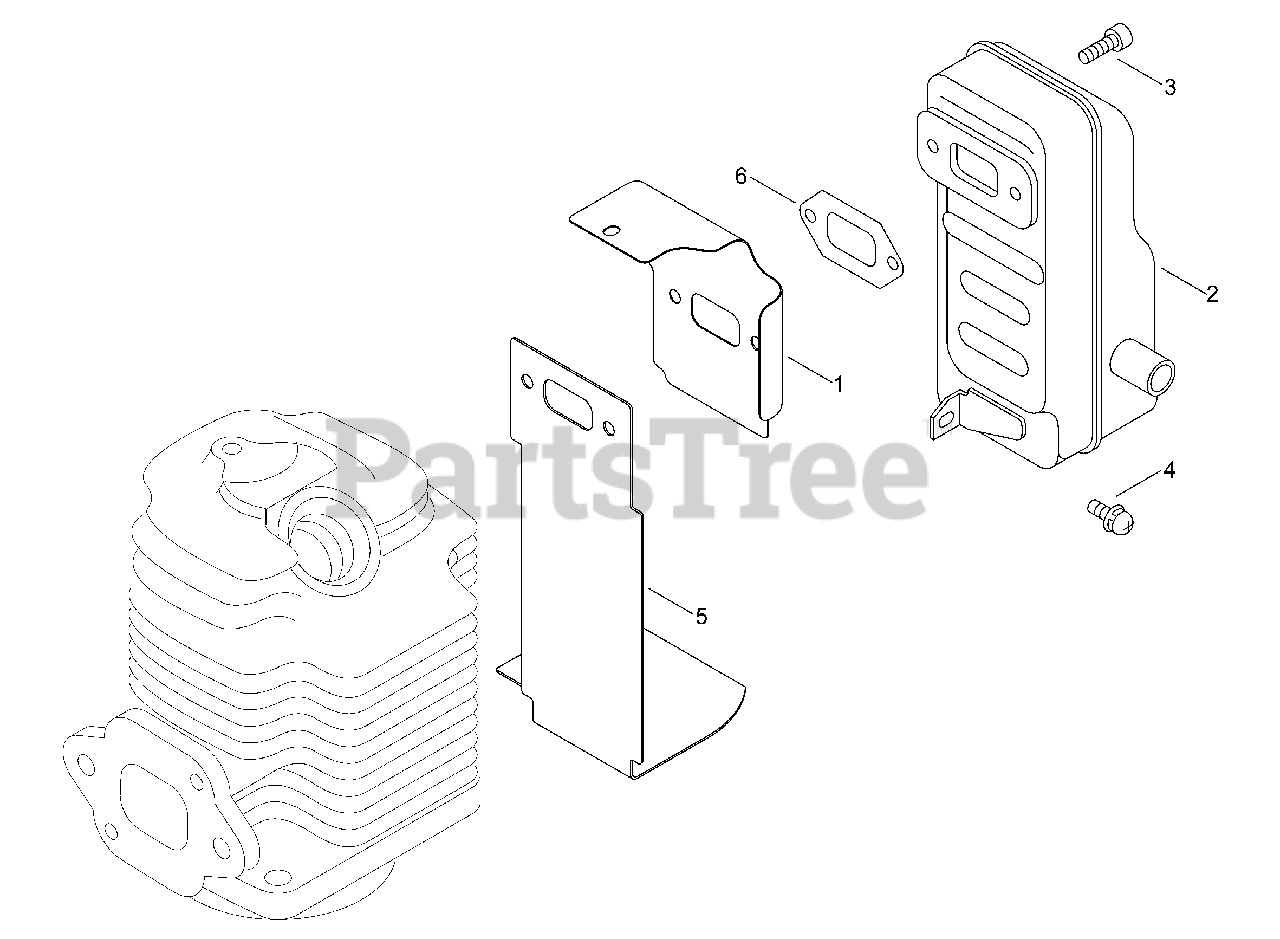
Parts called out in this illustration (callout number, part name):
1	COVER, ENGINE - EXHAUST
2	MUFFLER KIT
3	BOLT 6×20
4	SCREW 5×14
5	GASKET, EXHAUST
6	GASKET, MUFFLER
